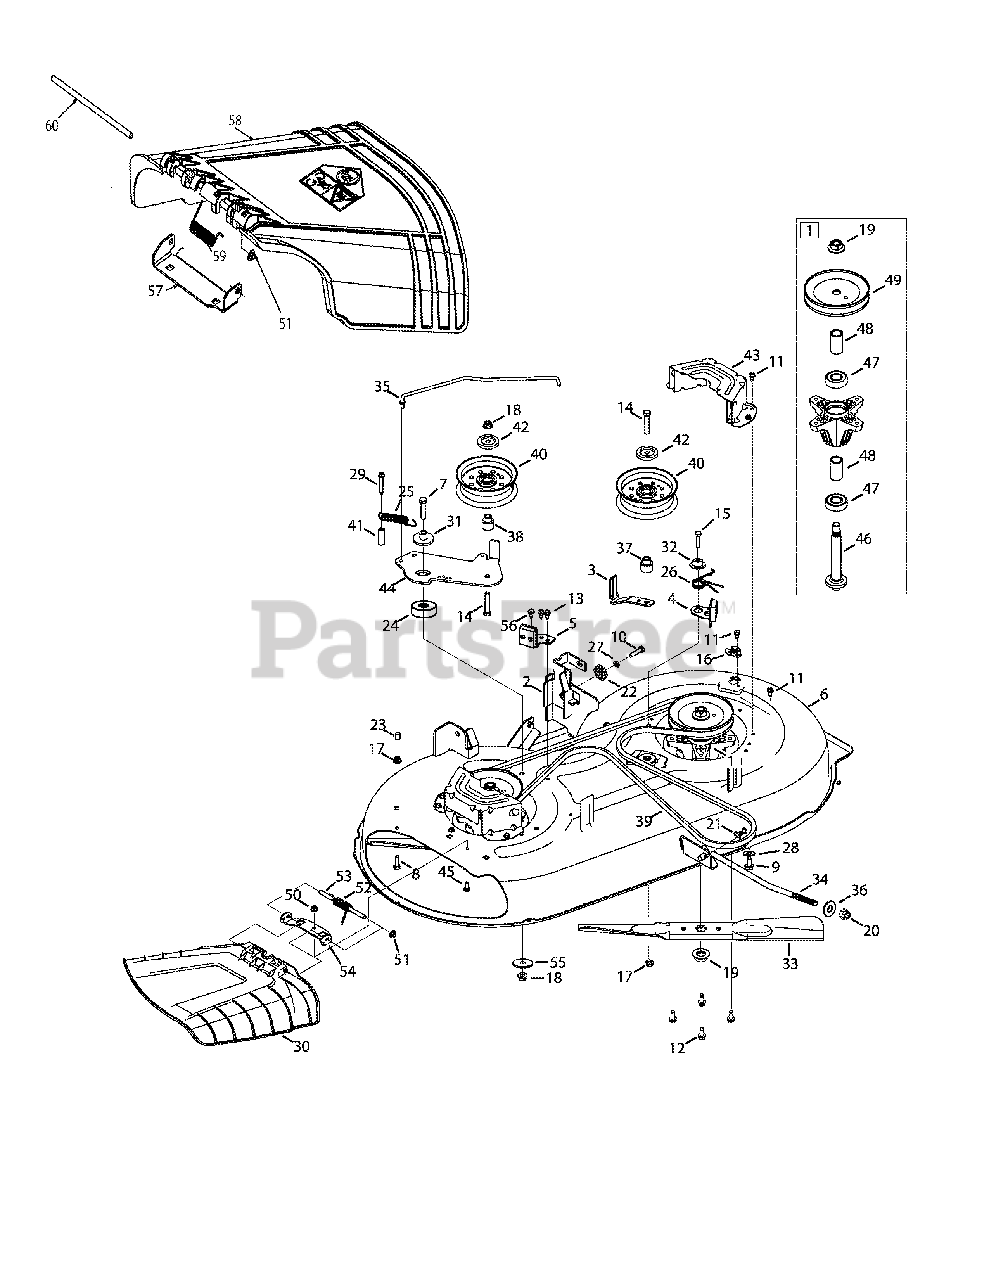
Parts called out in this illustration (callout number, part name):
1	Spindle Ass’y, Pulley, 6.2 Dia
2	Bracket Ass’y, Deck, Hanger LH
3	Belt Keeper
4	Brake Assembly, Deck, LH
5	Brake Assembly, Deck, RH
6	Deck, 42"
7	Hex Screw, 3/8-16 x 1.75
8	Hex Cap Screw, 5/16-18 x 1.00
9	Screw, Self-tapping, 5/16-18, .750
10	Hex Screw, 5/16-18, 1.25, Gr5, Std
11	Screw, Self-tapping, 1/4-20, 0.500
12	Screw, 5/16-18 x 0.750
13	Screw, M6-1 x .625
14	Hex Screw, 3/8-16, 2.00, Gr8, Std
15	Hex cap Screw, 5/16-18 x 1.25
16	Deck Wash Plug
17	Nut, Flange Lock, 5/16-18, Grf
18	Nut, Flange Lock, 3/8-16, Grf
19	Nut, Flange, 5/8-18
20	Flange Lock Nut, 1/2-13
21	Bow-Tie Cotter Pin
22	Gear, Deck, Adjustment
23	Cap, .290 x .500
24	Spacer, .385 x 1.75 x .585
25	Extension Spring, .750 X 4.77
26	Torsion Spring, LH
27	Washer, Lock, 5/16, Regular Duty
28	Flat Washer, .406 x .875 x .059
29	Screw, Self Tapping, 1/4-20, 1.50
30	Chute Deflector Assembly
31	Shoulder Spacer, .970 x .190
32	Shoulder Spacer, .75 x .145
33	Blade, Cut, 21.23" 2-In-1
34	Rod, Lift, Deck, Frt, 12.7
36	Deck Lift Pivot Cup
37	Shoulder Spacer, Idler
38	Shoulder Spacer, Pivot Idler
39	Belt, V Type, A Sec X 96.5
40	Pulley, Idler, 4.50"Dia
41	Spacer, .260 x .375 x 1.030
42	Pulley Cap
43	Deck Belt Cover, 42
44	Deck Idler Bracket
45	Hex Cap Screw, 1/4-20 x .62
46	Shift, Spindle, 6.11.
47	Bearing, Ball, .787id x 1.85 Odx.551
48	Spacer, .792 x 1.060 x 1.860
49	Pulley, Deck, 5.4 Dia
50	Nut, Flange Lock, 1/4-20, Nylon
51	Push Cap
52	Spring, Torsion, .440 ID x 1.75
53	Hinge Pin
55	Flat Washer, .406 x 1.50 x .105
56	Shoulder Screw, 1/4-20
57	Bracket, Chute, 42"
58	Chute Deflector Assembly
59	Spring, Torsion
60	Hinge Pin
